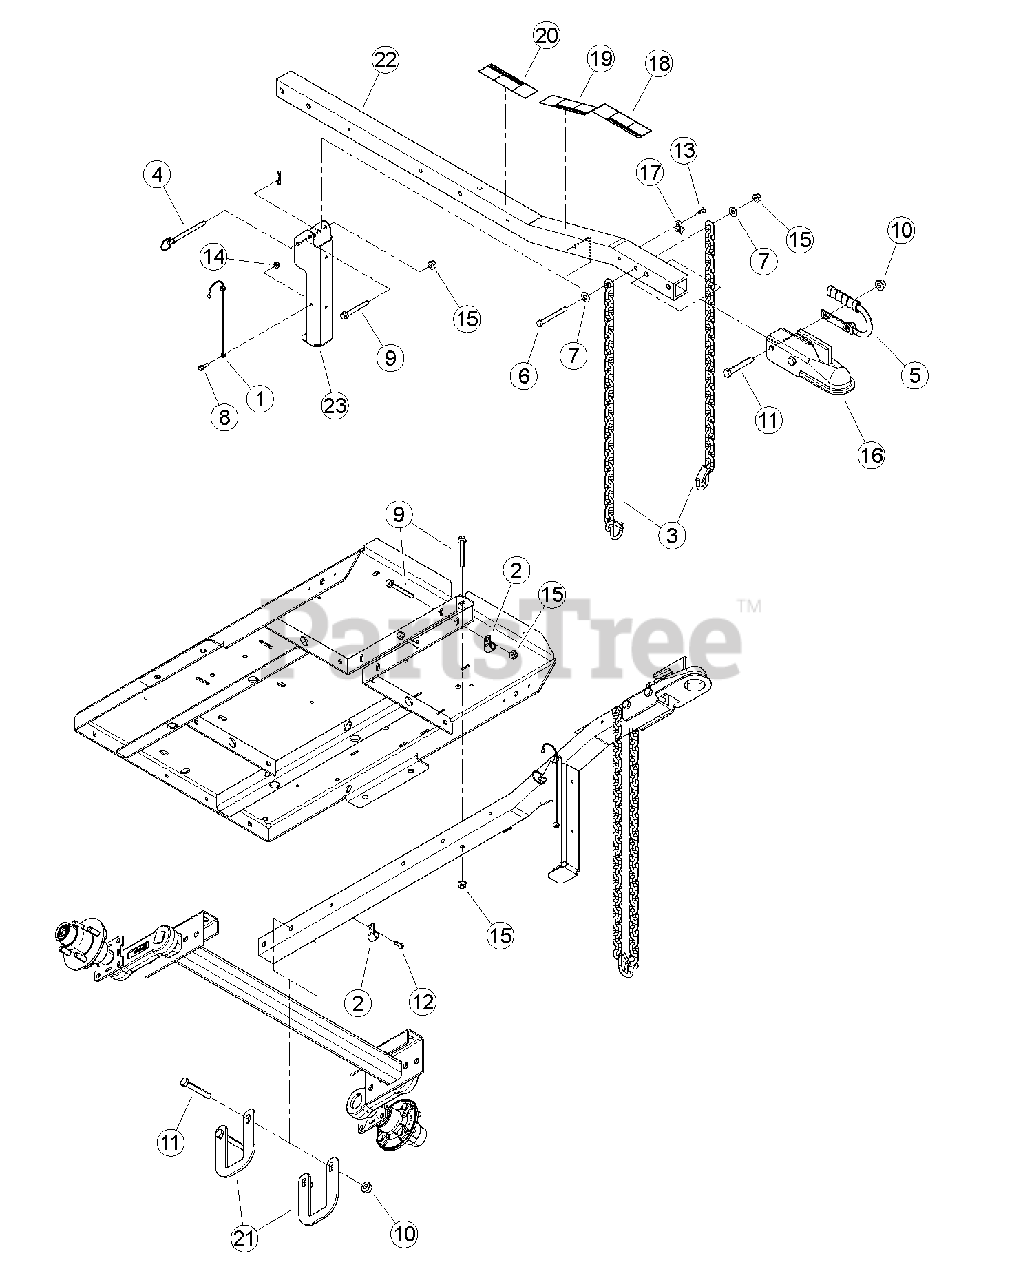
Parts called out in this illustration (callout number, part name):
1	LANYARD, NYLON
2	CLAMP, 9/16 COATED
3	CHAIN, SAFETY 5000 LB W/ LATCH
4	PIN, 3/8 HITCH
5	HANDLE, HITCH COUPLER
6	BOLT, 3/8 X 3-1/2" HEX HD GR5 ZP
7	WASHER, 3/8 FLAT
8	BOLT, 1/4-20 X 3/4 FLANGE GR5 CZP
9	BOLT, 3/8 X 3 FLANGE NC
10	NUT, 1/2-13 NYLOCK FLANGE
11	BOLT, 1/2 X 3-1/4 HCS GR5 ZP
12	SCREW, 11/32-12 X 7/8 FLANGE T-AB
13	RIVET, AL BLIND 1/4 X 3/4 DOME HEAD
14	NUT, 1/4-20 NYLOCK FLANGE
15	NUT, 3/8-16 NYLOCK FLANGE
16	COUPLER, TRAILER HITCH
17	CLAMP, CABLE MOUNT
18	DECAL, SAFETY CHAINS
19	DECAL, TRAILER ELECTRICAL
20	DECAL, SAFE COUPLING
21	PLATE, HITCH SADDLE
22	POLE, C/S HITCH
23	WELDMENT, STAND JACK
